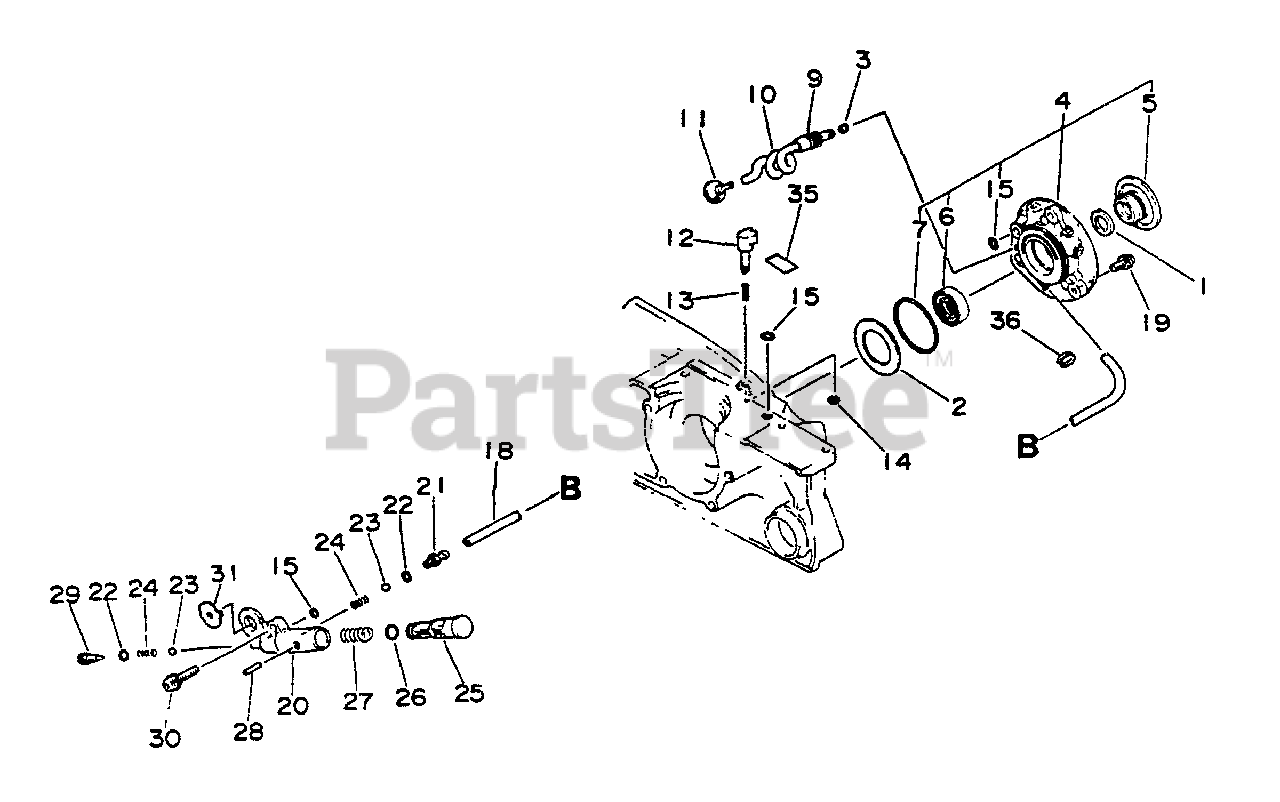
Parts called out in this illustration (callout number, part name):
2	PLATE
3	CLIP - 6.6
4	AUTO-OILER ASSY
5	WHEEL, WORM
6	SEAL, OIL
7	O-RING
10	PIPE, FUEL - SPIRAL
11	FILTER, OIL
12	DIAL, AUTO-OILER
14	RING, RETAINING - 3
15	O-RING - 3
18	PIPE - OIL
19	SCREW - 4X10
20	BODY, OIL PUMP
23	VALVE, BALL
24	SPRING, VALVE
25	PISTON, OIL PUMP
26	O-RING - 7
28	PIN - SPRING -- 2X16
29	ADAPTER, OIL PUMP
30	SCREW - 5X20
31	BRACKET, OIL PUMP
35	LABEL - CAUTION
36	CLIP - 6.6
